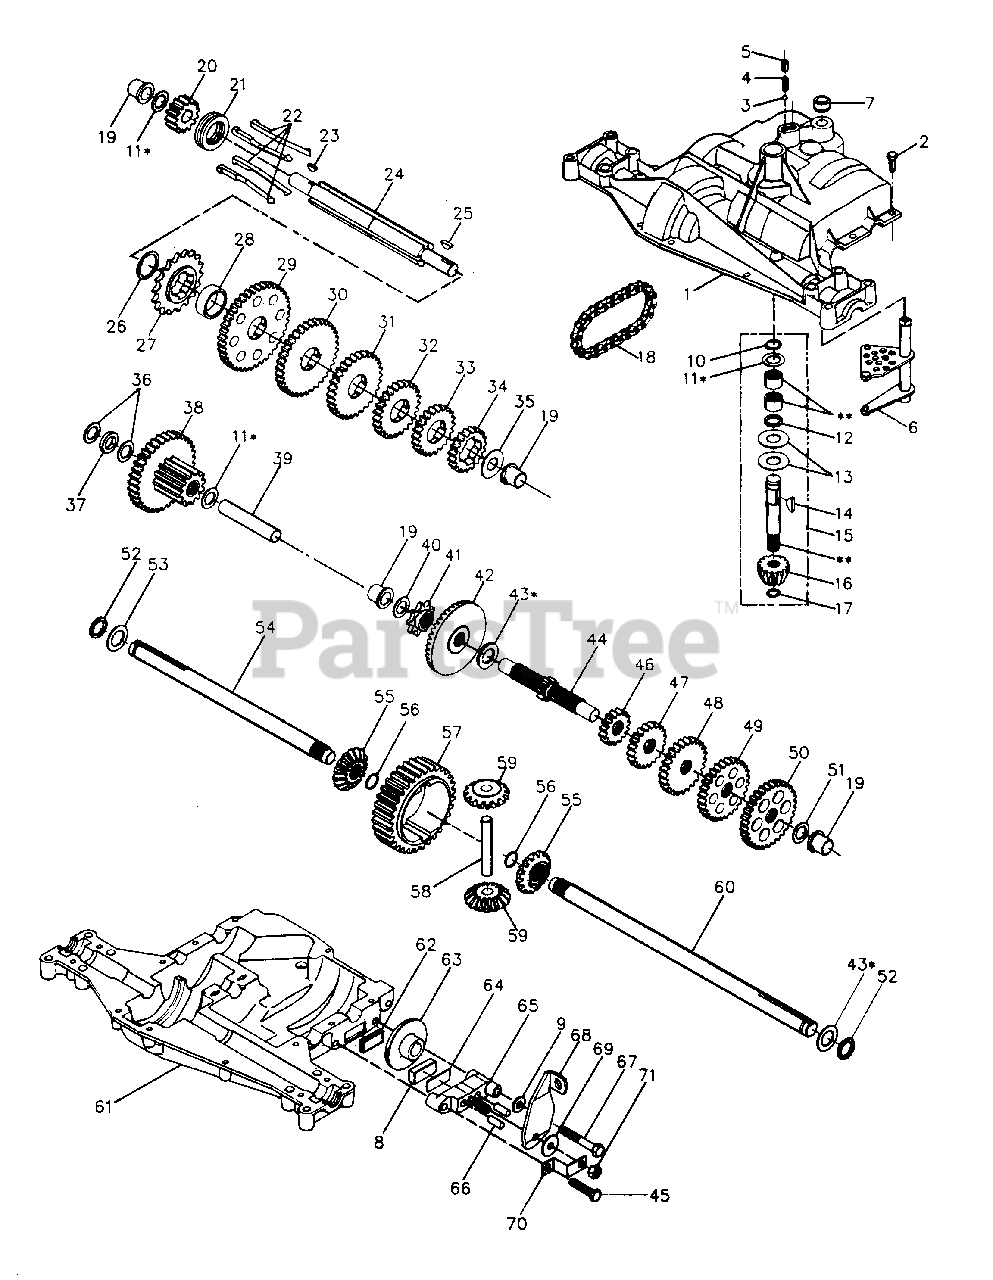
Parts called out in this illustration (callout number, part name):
1	Upper Housing (AYP part number)
2	Tapping Screw (Dana part number)
3	Detent Ball (Dana part number)
4	Detent Spring (Dana part number)
5	Screw Set (Dana part number)
6	Shifter Assembly (Dana part number)
8	Friction Puck (Dana part number)
9	Plain Washer
10	Retaining Ring (Dana part number)
11	Plain Washer .632 x 1.00 x .010 (Dana part number)
11	Plain Washer .632 x 1.00 x .020 (Dana part number)
11	Plain Washer .632 x 1.00 x .026 (Dana part number)
11	Plain Washer .632 x 1.00 x .031 (Dana part number)
11	Plain Washer .632 x 1.00 x .036 (Dana part number)
11	Plain Washer .632 x 1.00 x .041 (Dana part number)
11	Plain Washer .632 x 1.00 x .046 (Dana part number)
11	Plain Washer .632 x 1.00 x .050 (Dana part number)
11	Plain Washer .632 x 1.00 x .060 (Dana part number)
11	Plain Washer .632 x 1.00 x .082 (Dana part number)
11	O-Ring (Dana part number)
13	Plain Washer .632 x 1.38 x .046
14	Woodruff #9 Key
15	Input Shaft Assembly Kit (Dana part number)
16	14T Bevel Pinion (Dana part number)
17	Retaining Ring (Dana part number)
18	24 Pitches Chain (Dana part number)
19	Flange Bearing (Dana part number)
20	14T Spur Gear (Dana part number)
21	Clutch Collar (Dana part number)
22	Clutch Key (Dana part number)
23	Woodruff #3 Key
24	Intermediate Shaft (Dana part number)
25	Woodruff #61 Key (Dana part number)
26	Retaining Ring (Dana part number)
27	18T Sprocket (Dana part number)
28	Spacer (Dana part number)
29	40T Spur Gear (Dana part number)
30	35T Spur Gear
31	30T Spur Gear (Dana part number)
32	25T Spur Gear
33	22T Spur Gear (Dana part number)
34	19T Spur Gear (Dana part number)
35	Plain Washer (Dana part number)
36	Plain Washer .632 x 1.00 x .026
37	Spacer (Dana part number)
38	Comb. Gear Assembly (Dana part number)
39	Idler Shaft (Dana part number)
40	Plain Washer
41	9T Sprocket (Dana part number)
42	42T Bevel Gear (Dana part number)
43	Plain Washer .758 x 1.12 x .010 (Dana part number)
43	Plain Washer .758 x 1.12 x .015 (Dana part number)
43	Plain Washer .758 x 1.12 x .020 (Dana part number)
43	Plain Washer .758 x 1.12 x .025 (Dana part number)
43	Plain Washer .758 x 1.12 x .031 (Dana part number)
43	Plain Washer .758 x 1.12 x .035 (Dana part number)
43	Plain Washer .758 x 1.12 x .040(Dana part number)
43	Plain Washer .758 x 1.12 x .045 (Dana part number)
43	Plain Washer .758 x 1.12 x .050 (Dana part number)
44	Drive Shaft (Dana part number)
45	Tapping Screw (Dana part number)
46	15T Spur Gear (Dana part number)
47	20T Spur Gear (Dana part number)
48	25T Spur Gear (Dana part number)
49	28T Spur Gear (Dana part number)
50	31T Spur Gear (Dana part number)
51	Plain Washer (Dana part number)
52	Felt Seal (Dana part number)
53	Plain Washer (Dana part number)
54	L.H. Axle (Dana part number)
55	15T Miter Gear (Dana part number)
56	Retaining Ring (Dana part number)
57	32T Spur Gear (Dana part number)
58	Cross Shaft (Dana part number)
59	15T Miter Gear (Dana part number)
60	R.H. Axle (Dana part number)
61	Lower Housing (AYP part number)
62	Friction Puck (Dana part number)
63	Brake Disc(Dana part number)
64	Spacer (Dana part number)
65	Brake Jaw (Dana part number)
66	Dowel Pin (Dana part number)
67	Tapping Screw (Dana part number)
68	Actuating Lever
69	Plain Washer
70	Anti-Rotation Bracket (Dana part number)
71	Locknut (Dana part number)
72	Grease (Dana part number)
